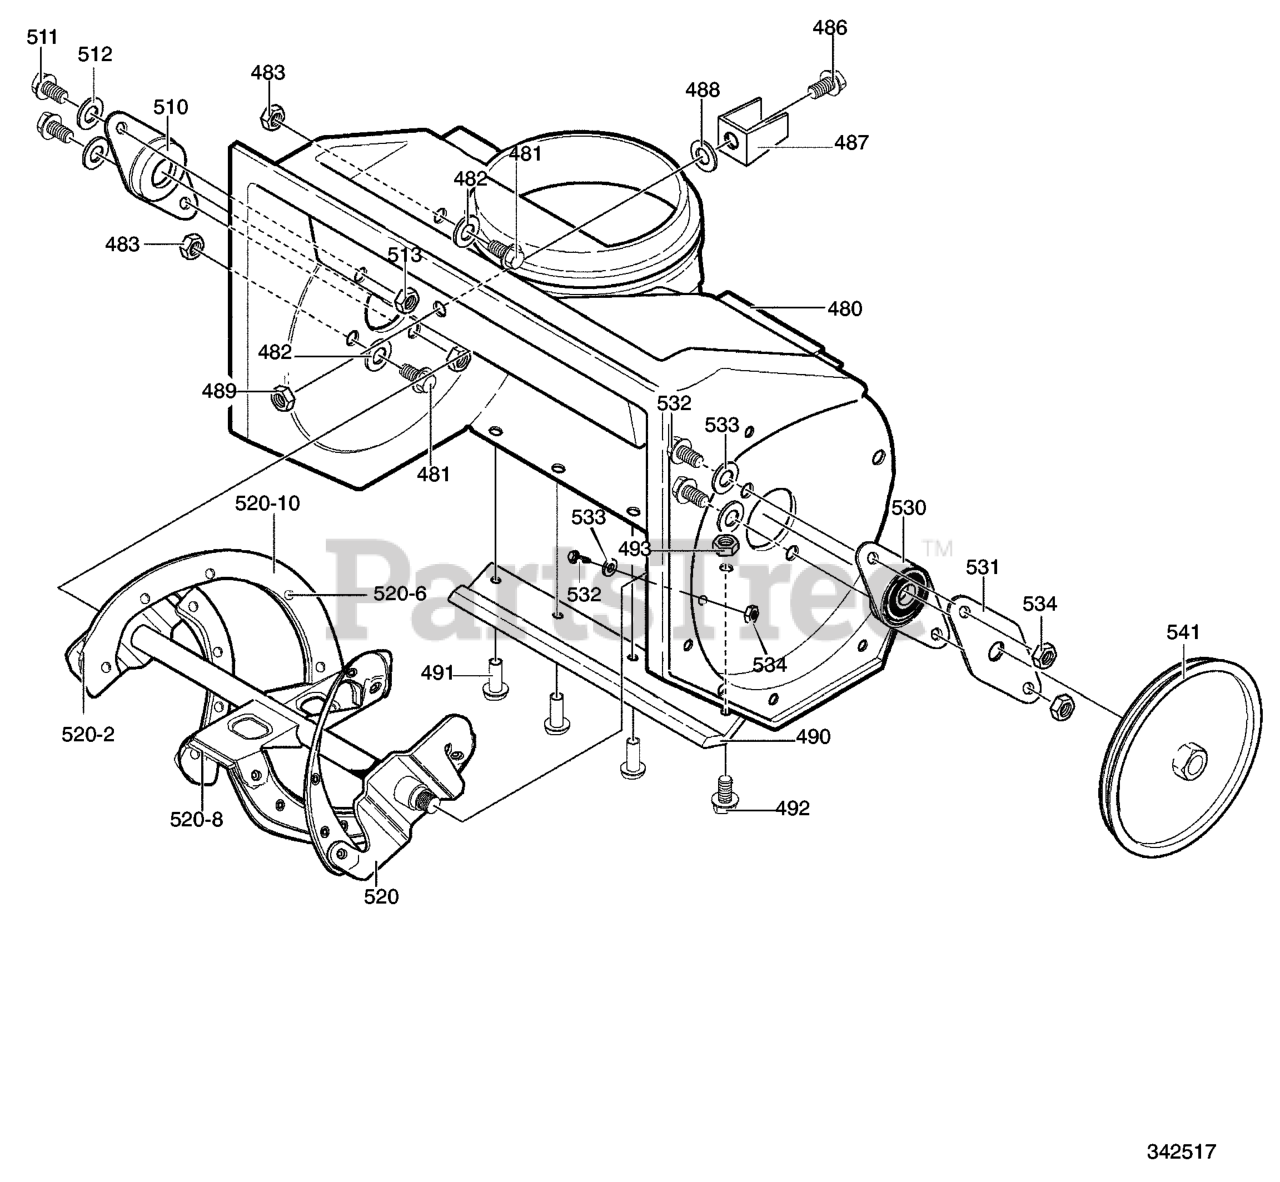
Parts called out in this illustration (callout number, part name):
480	HOUSING, ASSY
481	SCREW, 1/4-20X.75
482	WASHER, FLAT .281X.63X.065
483	NUT, HEX 1/4-20 YZ
486	SCREW, 1/4-20X.63
487	BRACKET, STOP
488	WASHER, FLAT .333X.87X.119
489	NUT, 1/4-20 HEX NYLOCK
490	BLADE, SCRAPER
491	RIVET, OVSET
492	SCREW, 1/4-20X.75
493	NUT, 1/4-20 YZ
510	BEARING, FLANGE
511	SCREW, 1/4-20X1.00
512	WASHER, FLAT .281X.63X.065
513	NUT, 1/4-20
520	AUGER, ASSY
520-2	BLADE, AUGER
520-6	RIVET
520-8	BLADE, CENTER
520-10	AUGER & BLADE SUPPORT
530	BEARING & PLATE ASSY
531	PLATE, RETAINER
532	SCREW, 1/4-20X.63
533	WASHER, FLAT .281X.63X.065
534	NUT, 1/4-20
